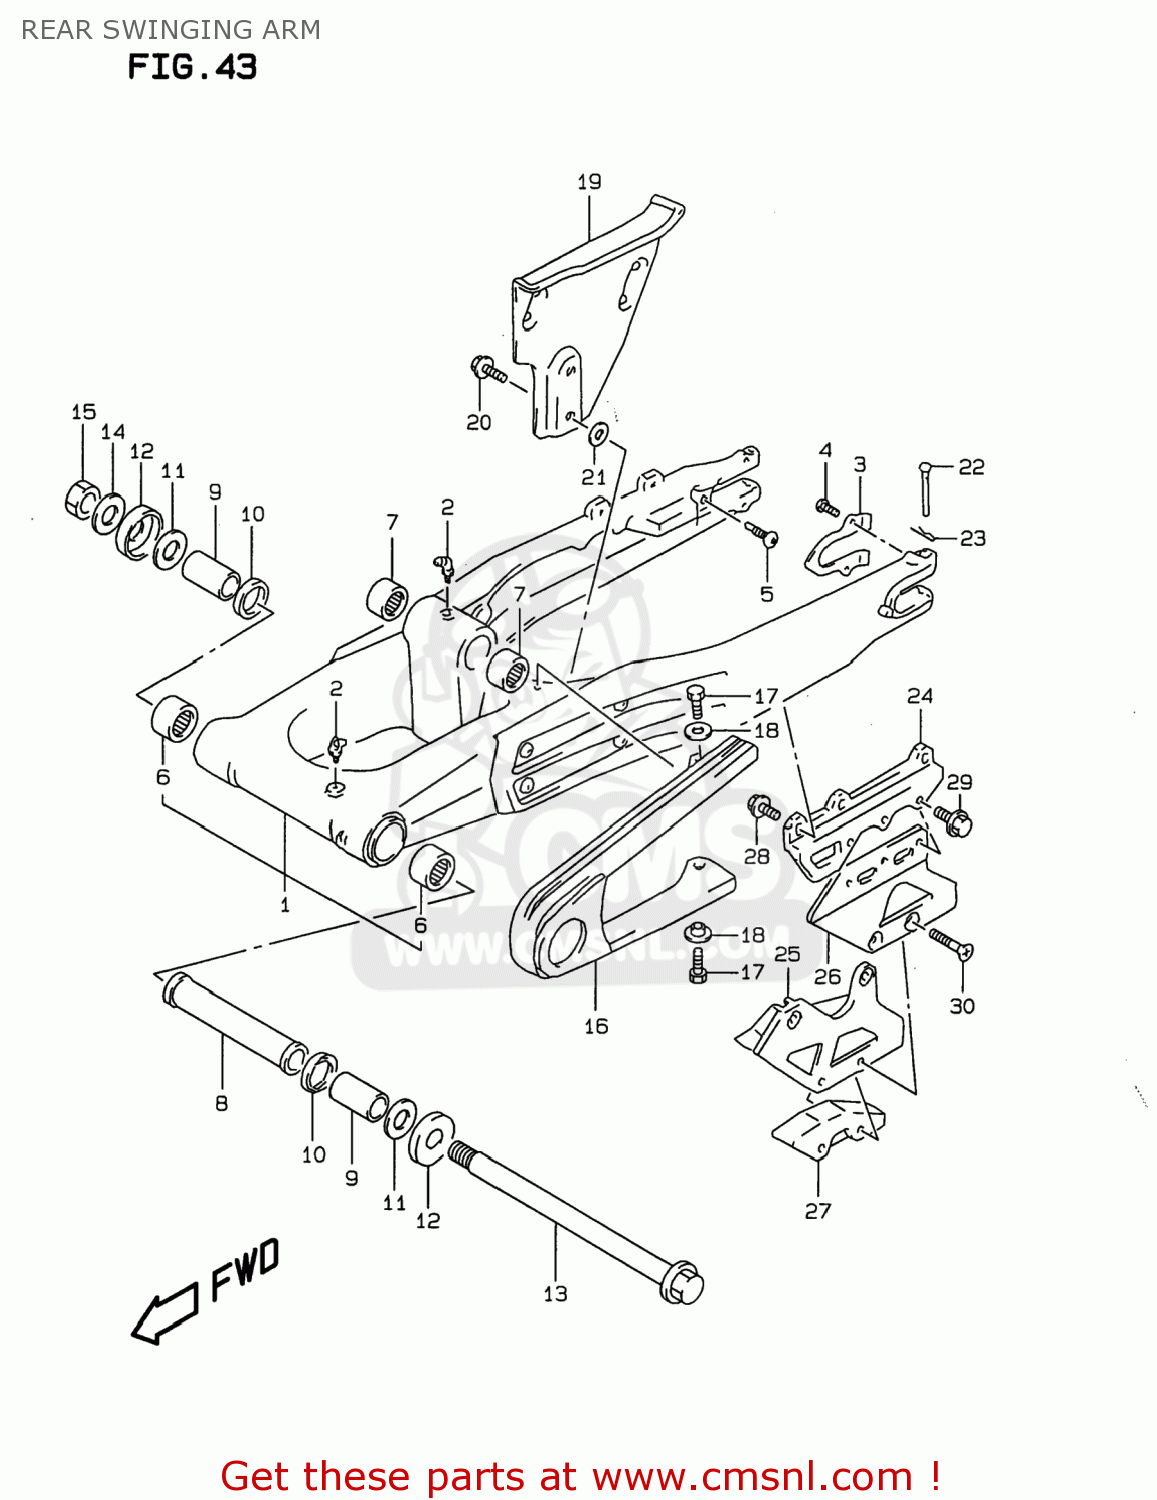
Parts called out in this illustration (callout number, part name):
1	SWING ARM ASSEMBLY,REAR
2	NIPPLE,GREASE
3	PLATE,SWING ARM RR
4	SCREW (5X8)
5	SCREW (M10X21)
6	BEARING(22X29X30)
7	BEARING(20X27X23.5)
8	SPACER,SWING ARM PIVOT,CENTER
9	SPACER,SWGARM PIVOT BRG
10	SEAL,OIL(22X29X4)
11	WASHER
12	COVER,SWINGINGARM PIVOT
13	SHAFT,SWINGING ARM PIVOT
14	WASHER, FIXED DRIVE FACE
15	NUT
16	BUFFER,CHAIN TOUCH DEFENSE
17	BOLT
18	WASHER
19	GUARD,CHAIN
20	BOLT
21	WASHER(6.5X16X4)
22	PIN
23	CLIP
24	BRACKET,CHAIN GUIDE
25	GUIDE,CHAIN
26	PLATE,CHAIN GUIDE OUTER
27	DEFENSE,CHAIN GUIDE
28	BOLT
29	SCREW
30	SCREW(6X40)
